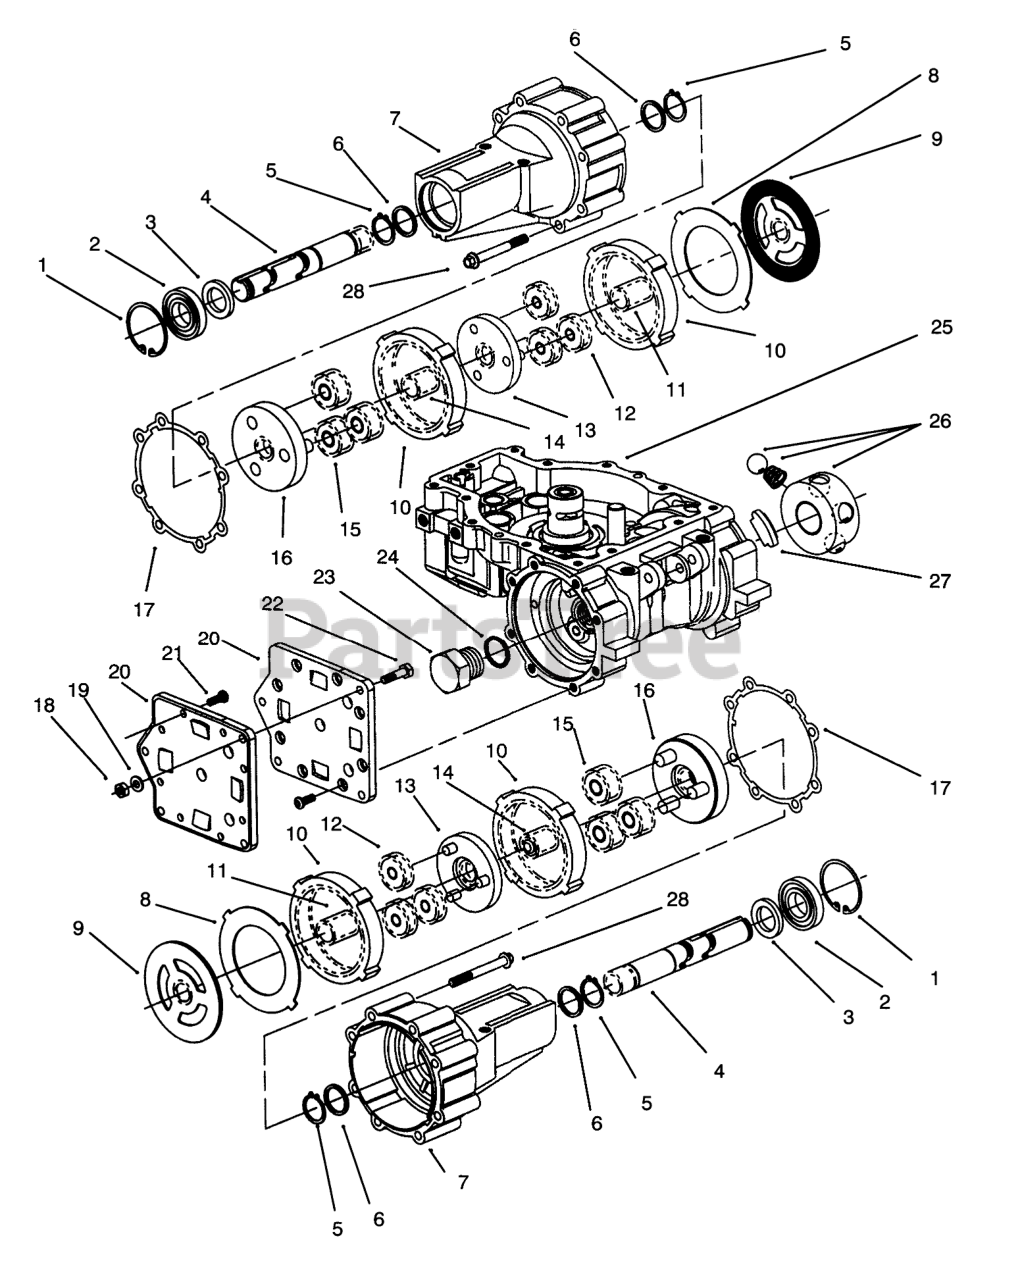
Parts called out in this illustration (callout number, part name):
1	RETAINING RING
2	BALL BEARING
3	RADIAL LIP SEAL
4	AXLE SHAFT
5	RETAINING RING
6	THRUST WASHER
7	AXLE HOUSING
8	BACKUP PLATE
9	REACTION PLATE
10	57 TOOTH RING GEAR
11	15 TOOTH FIRST GEAR
12	15 TOOTH PRIMARY CARR.
13	21 TOOTH PLANET. GEAR
14	15 TOOTH SECOND GEAR
15	21 TOOTH SECOND GEAR
16	15 TOOTH SECOND GEAR
17	AXLE HOUSING GASKET
18	HEX NUT
19	LOCKWASHER
20	FLANGE
21	1/4 TORX BUTRESS HD SC
22	HEX HD CAPSCREW
23	PLUG ASM
24	"O" RING SEAL
25	HOUSING ASM
26	Motor Assembly
27	Pad Assembly
28	5/16 HEX HEAD SCREW
